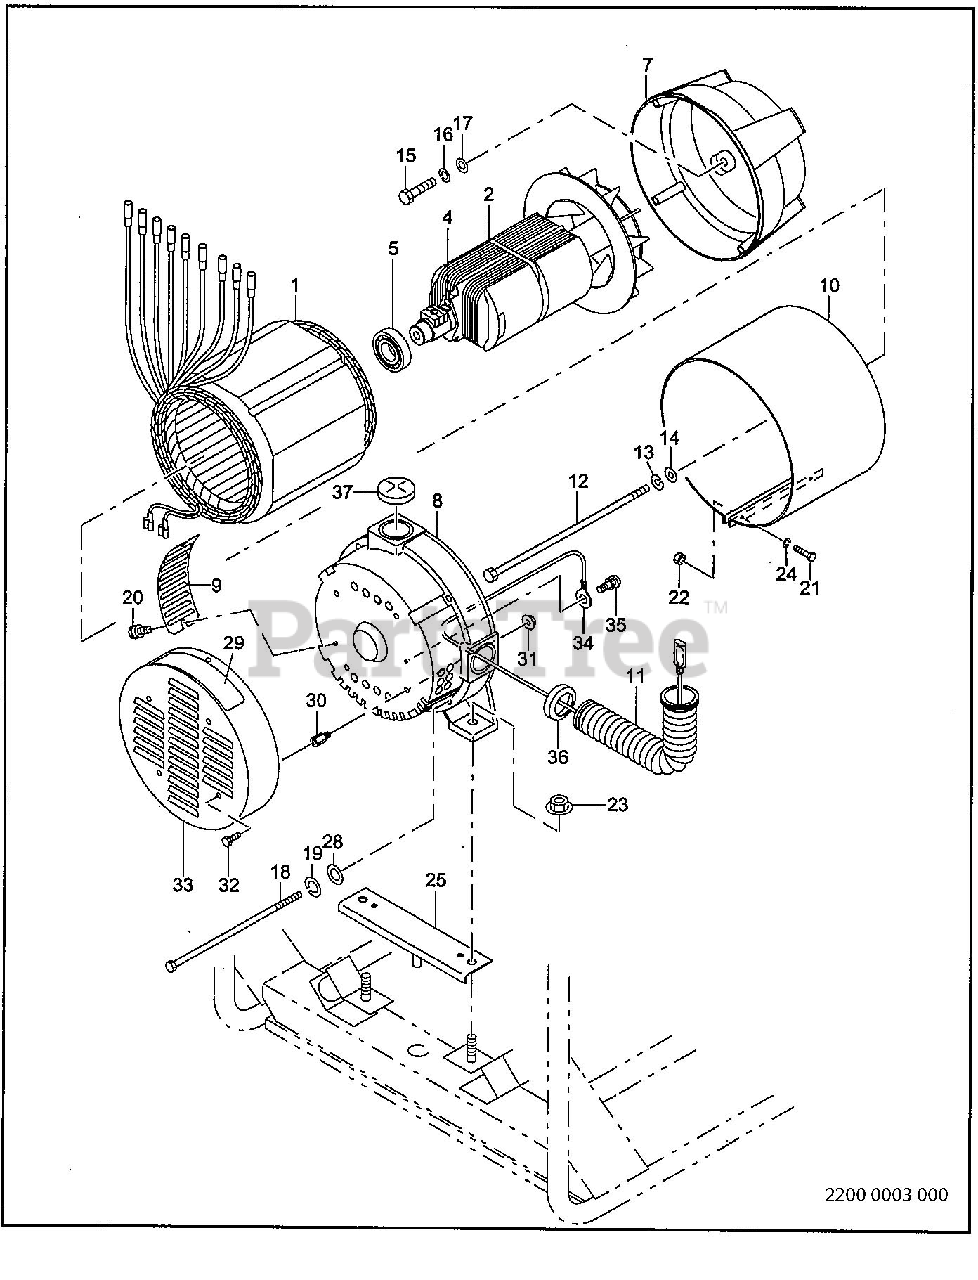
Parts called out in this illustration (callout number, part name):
1	STATOR ASSY
2	ROTOR ASSY
12	THROUGH BOLT
15	BOLT
20	BOLT and WASHER ASSY
21	BOLT
23	FLANGE NUT
25	GENERATOR BASE
29	LABEL(SPEC)
35	SCREW and WASHER
